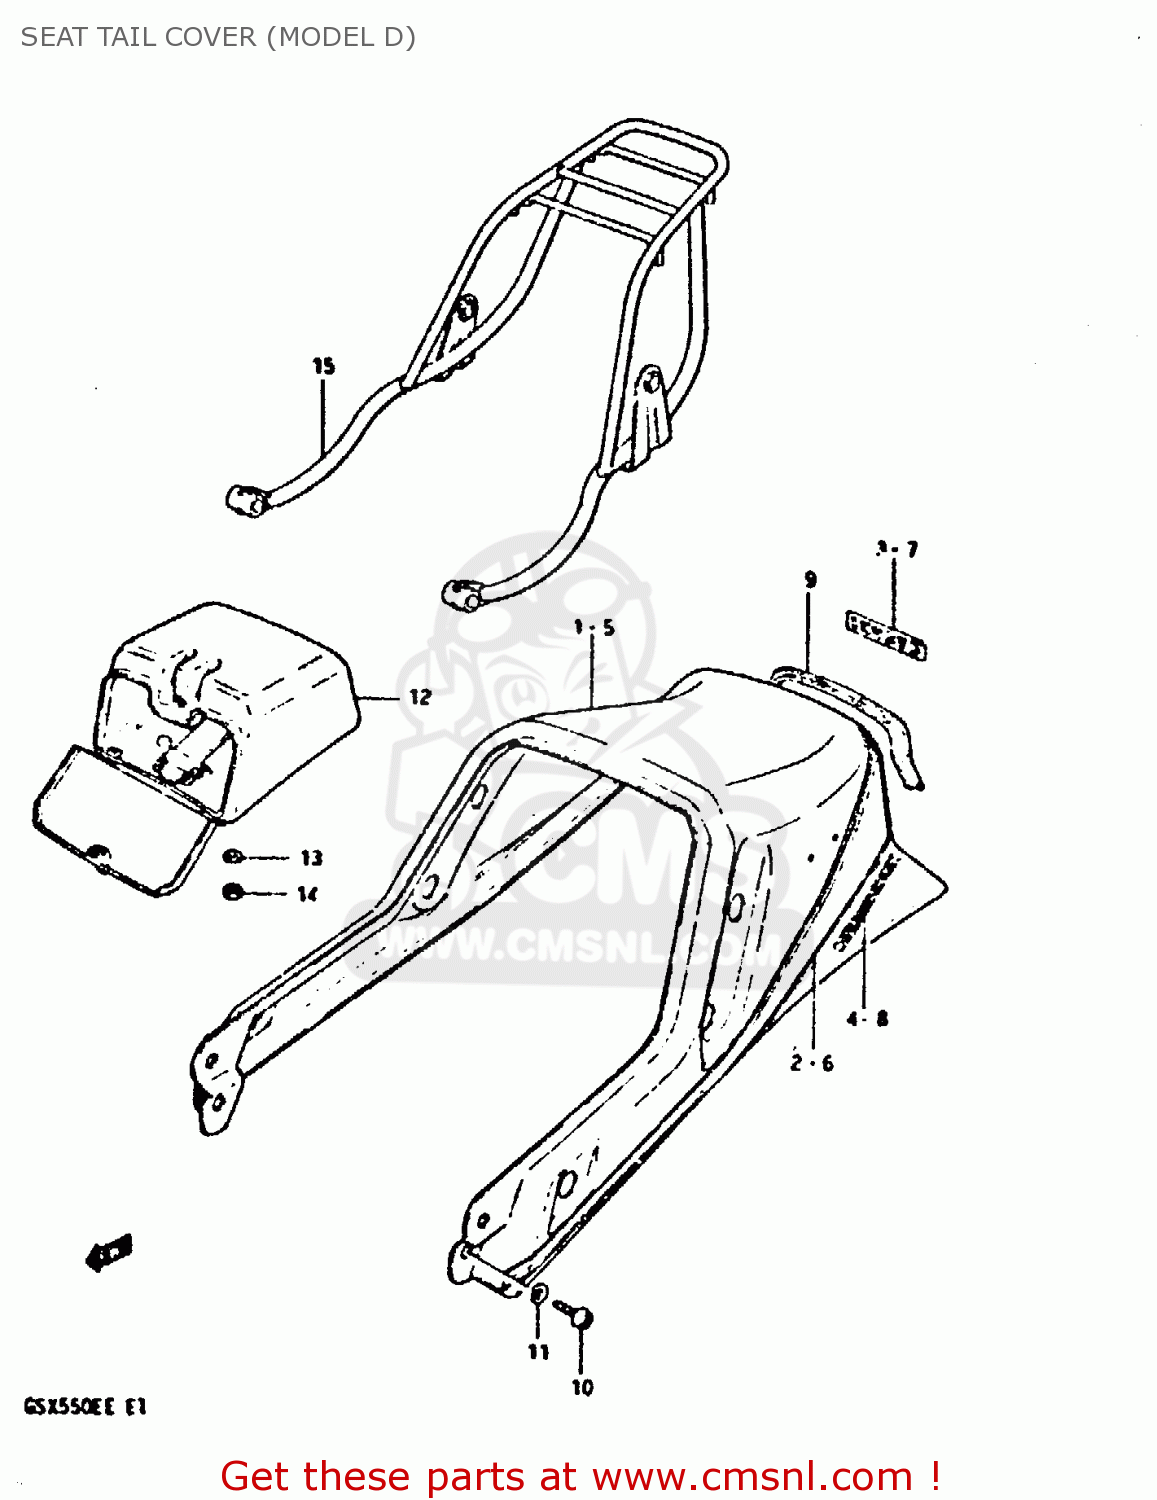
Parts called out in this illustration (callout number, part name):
1	TAIL COVER, SEAT
2	TAPE SET,SEAT TAIL COVER
3	EMBLEM(WHITE)
4	EMBLEM
5	TAIL COVER, SEAT
6	TAPE SET,SEAT TAIL COVER
7	EMBLEM(WHITE)
8	EMBLEM
9	BLIND,SEAT TAIL COVER
10	SCREW
11	LOCK WASHER
12	BOX,SEAT TAIL
13	WASHER
14	NUT
15	CARRIER, SPORTS
